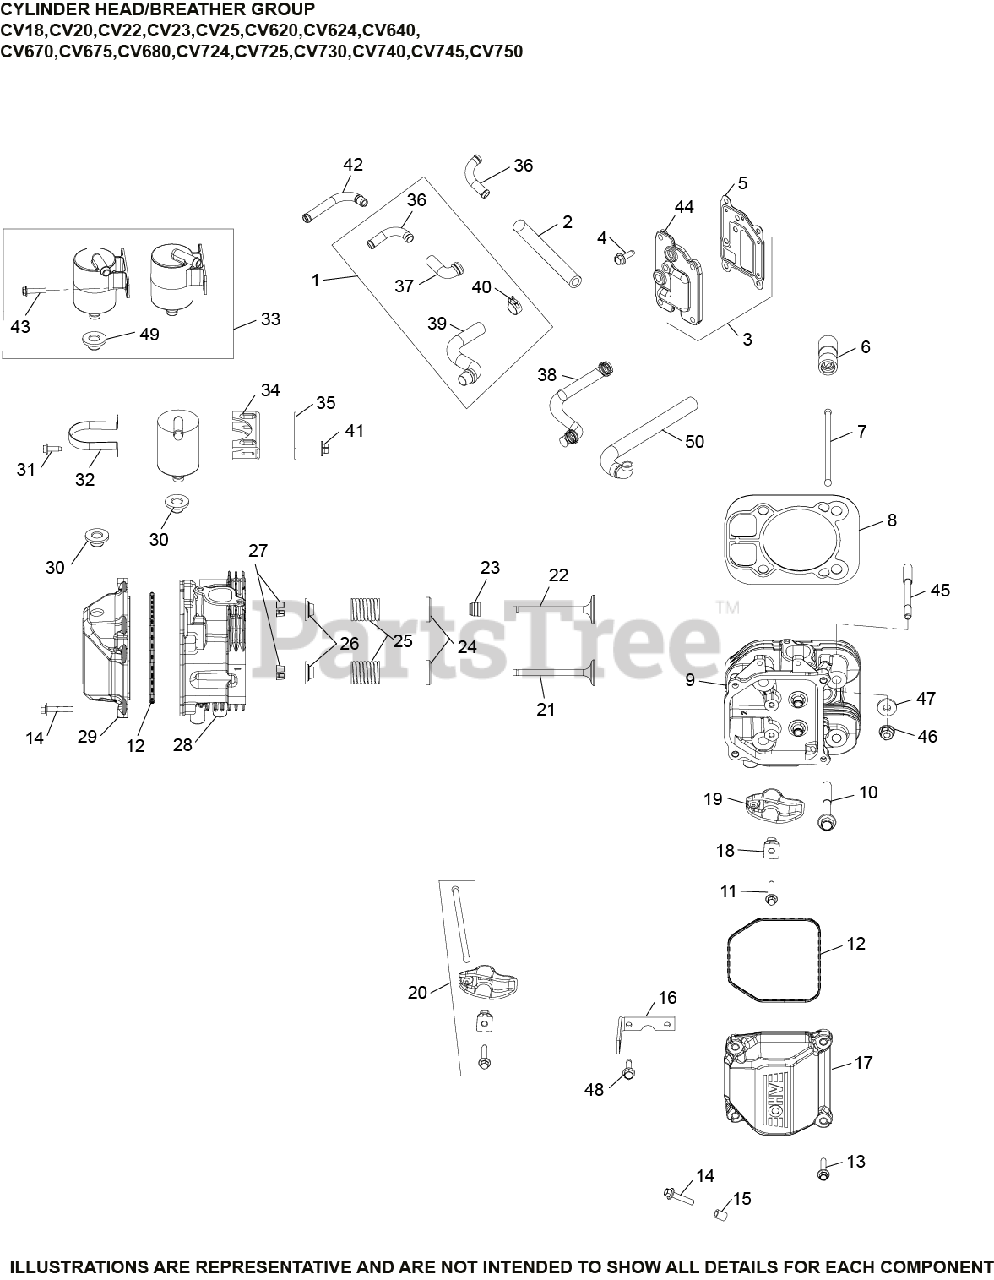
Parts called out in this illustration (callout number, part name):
4	SCREW, THREAD FORMING
5	GASKET, BREATHER
6	LIFTER, VALVE HYDRAULIC - (#2535111S)
7	ROD, PUSH
8	KIT, CYLINDER HEAD GASKET
9	KIT, #2 CYLINDER HEAD USE 24 318 172-S
11	SCREW, FLG M6X1.0X34
12	O-RING (YELLOW), VALVE COVER
14	SCREW, FLG M6X1.0X30
16	STRAP, LIFT
17	KIT, VALVE COVER-PLAIN
18	PIVOT, ROCKER ARM
19	ARM, ROCKER
20	KIT, VALVE TRAIN
21	VALVE, EXHAUST (STD) - USE 32 016 01-S
21	VALVE, EXHAUST (.25)
22	VALVE, INTAKE (STD)
22	VALVE, INTAKE (.25)
23	SEAL, VALVE BAND
24	RETAINER, SPRING
25	SPRING, VALVE
26	CAP, VALVE SPRING
27	KIT, RETAINER
28	KIT, #1 CYLINDER HEAD USE 24 318 171-S
29	KIT, VALVE COVER
33	KIT, BREATHER SEPARATOR
41	NUT, PLASTIC
43	SCREW, HEX FLANGE HI-LO
44	KIT, BREATHER COVER
45	STUD, M8X1.25
46	NUT, FLG M8X1.25
47	WASHER, FLAT 8.6 MM
48	SCREW, THREAD FORMING
49	GROMMET, RUBBER
